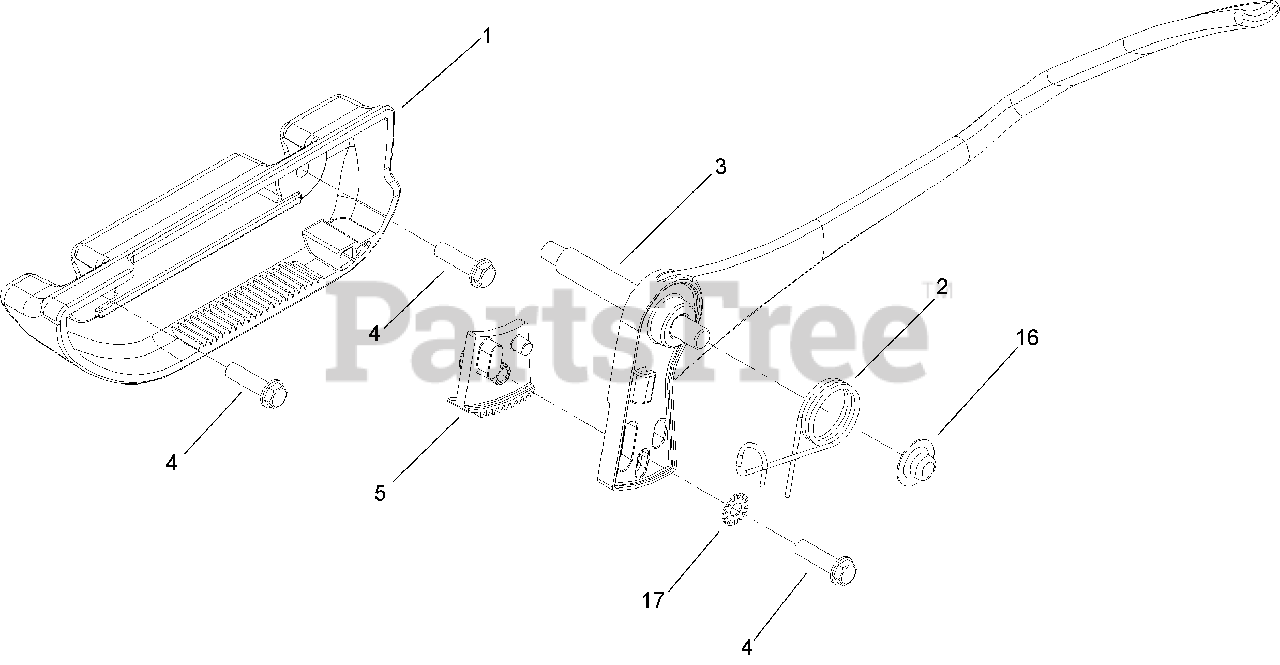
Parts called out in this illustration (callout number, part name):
1	HOUSING-CRUISE CONTROL
2	SPRING-TORSION
3	LEVER ASM
4	SCREW-HWH
5	GEAR-CRUISE CONTROL
16	RETAINER-PUSH ON
17	WASHER-LOCK
